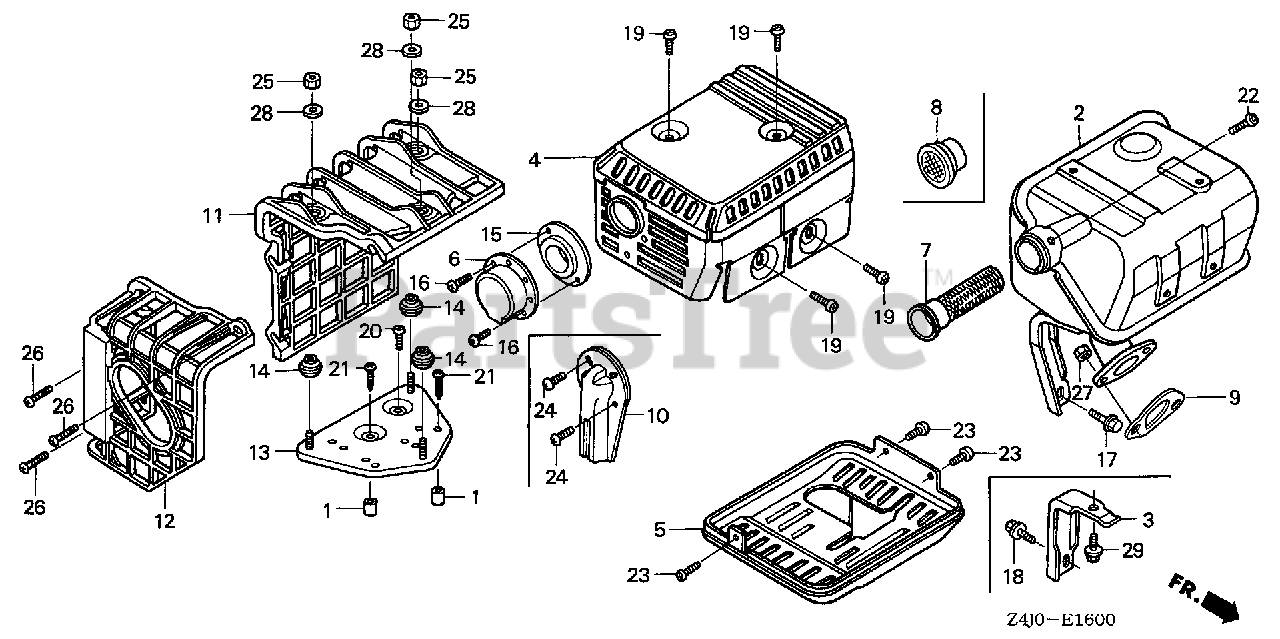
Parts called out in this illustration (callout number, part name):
1	COLLAR, AIR CLEANER HOUSING
2	MUFFLER (ARRESTER) (SPARK ARRESTER TYPE)
2	MUFFLER (SILENT)
3	STAY, MUFFLER
4	PROTECTOR, MUFFLER
4	PROTECTOR, MUFFLER (SILENT)
7	ARRESTER, SPARK
8	NETTING, WIRE FLANGE
9	GASKET, MUFFLER
11	COVER, MUFFLER
12	COVER, RR. MUFFLER
13	BASE, MUFFLER COVER
14	SPACER, MUFFLER COVER
18	BOLT, FLANGE (6X13)
19	SCREW, TAPPING (5X8)
20	SCREW, TAPPING (5X8)
21	SCREW, TAPPING (5X25)
22	SCREW, TAPPING (4X6) (TO INSTALL OPTIONAL SPARK ARRESTER)
22	SCREW, TAPPING (4X6)
25	NUT, HEX. (5MM)
26	SCREW-WASHER (6X20)
27	NUT, HEX. (8MM)
28	WASHER, PLAIN (5MM)
29	BOLT, FLANGE (6X12) Use up to Engine SN 1543277.
